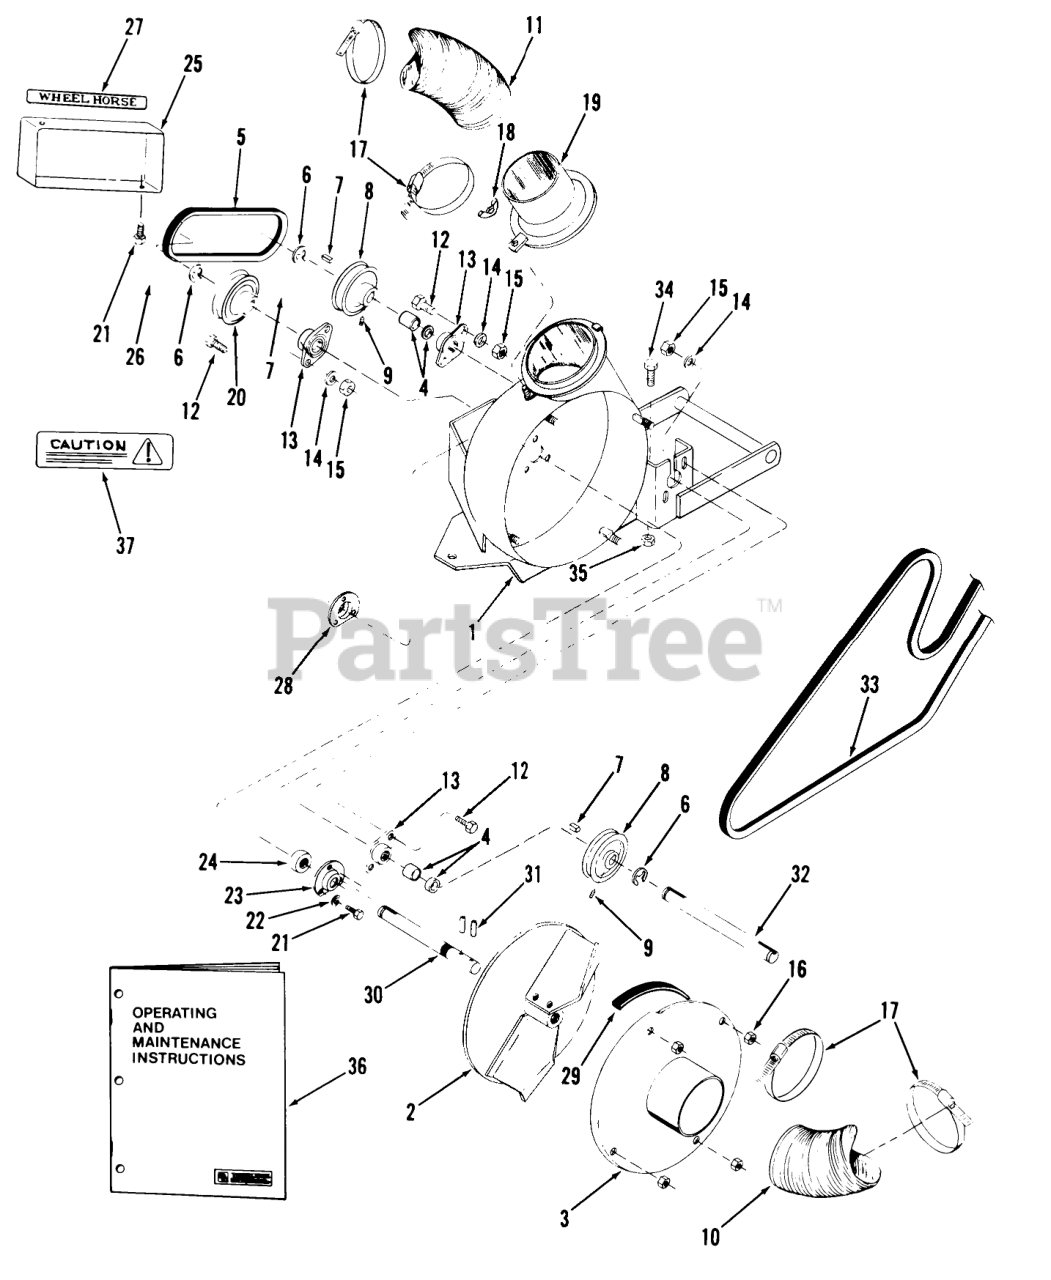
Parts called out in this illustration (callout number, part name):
1	Impeller Housing-97-42VC02 Only
2	Impeller
3	Front Plate
4	Spacer-Jackshaft (Thick), Input Side-07-42VC01
4	Spacer-Jackshaft (Thin), Impeller Side-07-42VC01
5	V-BELT
6	E-Ring 3/4
7	KEY
8	JACKSHAFT PULLEY
9	Set Screw
10	6" Dia. Hose x 51"
12	Bolt
13	BEARING-JACKSHAFT
14	Washer
15	Nut
16	Nut
17	CLAMP
18	WING NUT
19	TRANSITION HOSE
20	Impeller Pulley
21	S.T. Screw #8-32 x 1/2
22	Washer
23	BEARING-CUP
24	BEARING-BALL
25	Belt Cover-97-42VC02 Only
26	Nut
27	Decal-Rear
28	BEARING-CUP W/NUTS
30	SHAFT
31	ROLL PIN 1/4 X 1-1/4
32	JACKSHAFT
33	BELT-VEE
34	H H C S
35	Nut
36	Operating and Maintenance Instructions
37	DECAL-CAUTION
